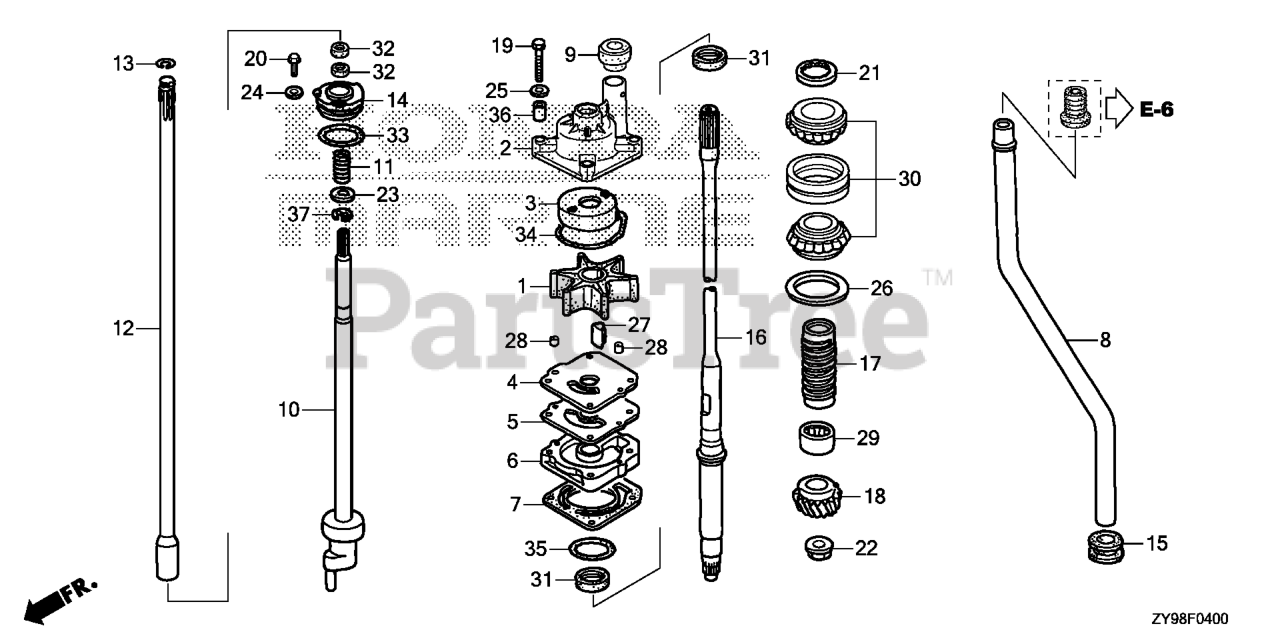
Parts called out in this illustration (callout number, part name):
1	IMPELLER, PUMP
2	HOUSING, IMPELLER
3	LINER, PUMP
4	COVER, IMPELLER
5	GASKET B, IMPELLER
6	HOUSING, WATER PUMP
7	GASKET, WATER PUMP
8	TUBE, WATER (XL)
9	RING, WATER TUBE SEAL
10	ROD, SHIFT (L)
11	SPRING, SHIFT ROD
12	ROD A, SHIFT (XL)
13	RING, STOPPER
14	HOLDER, SHIFT ROD
15	GROMMET, EXTENSION CASE
16	SHAFT, VERTICAL (UL)
17	SLINGER, OIL
18	GEAR, PINION (12T)
19	BOLT, HEX. (8X55)
20	BOLT, FLANGE (6X12) Use from Frame SN 1005249.
21	NUT, LOCK (64MM)
22	NUT, HEX. (16MM)
23	WASHER, PLAIN (12MM)
24	WASHER, PLAIN (6MM)
25	WASHER (8MM)
26	SHIM A, GEAR (0.10)
26	SHIM B, GEAR (0.15)
26	SHIM C, GEAR (0.30)
26	SHIM D, GEAR (0.50)
27	KEY, WOODRUFF
28	PIN, DOWEL (6X10)
29	BEARING, NEEDLE (1-1/8X1-1/2X1-1/4)
30	BEARING, TAPER ROLLER (30X62X40)
31	SEAL, WATER (23X36X6)
32	SEAL, WATER (12X21X6)
33	O-RING (49.4X3.1)
34	O-RING, WATER PUMP
35	O-RING (58.5X3.5)
36	COLLAR, DISTANCE
37	E-RING (10MM)
